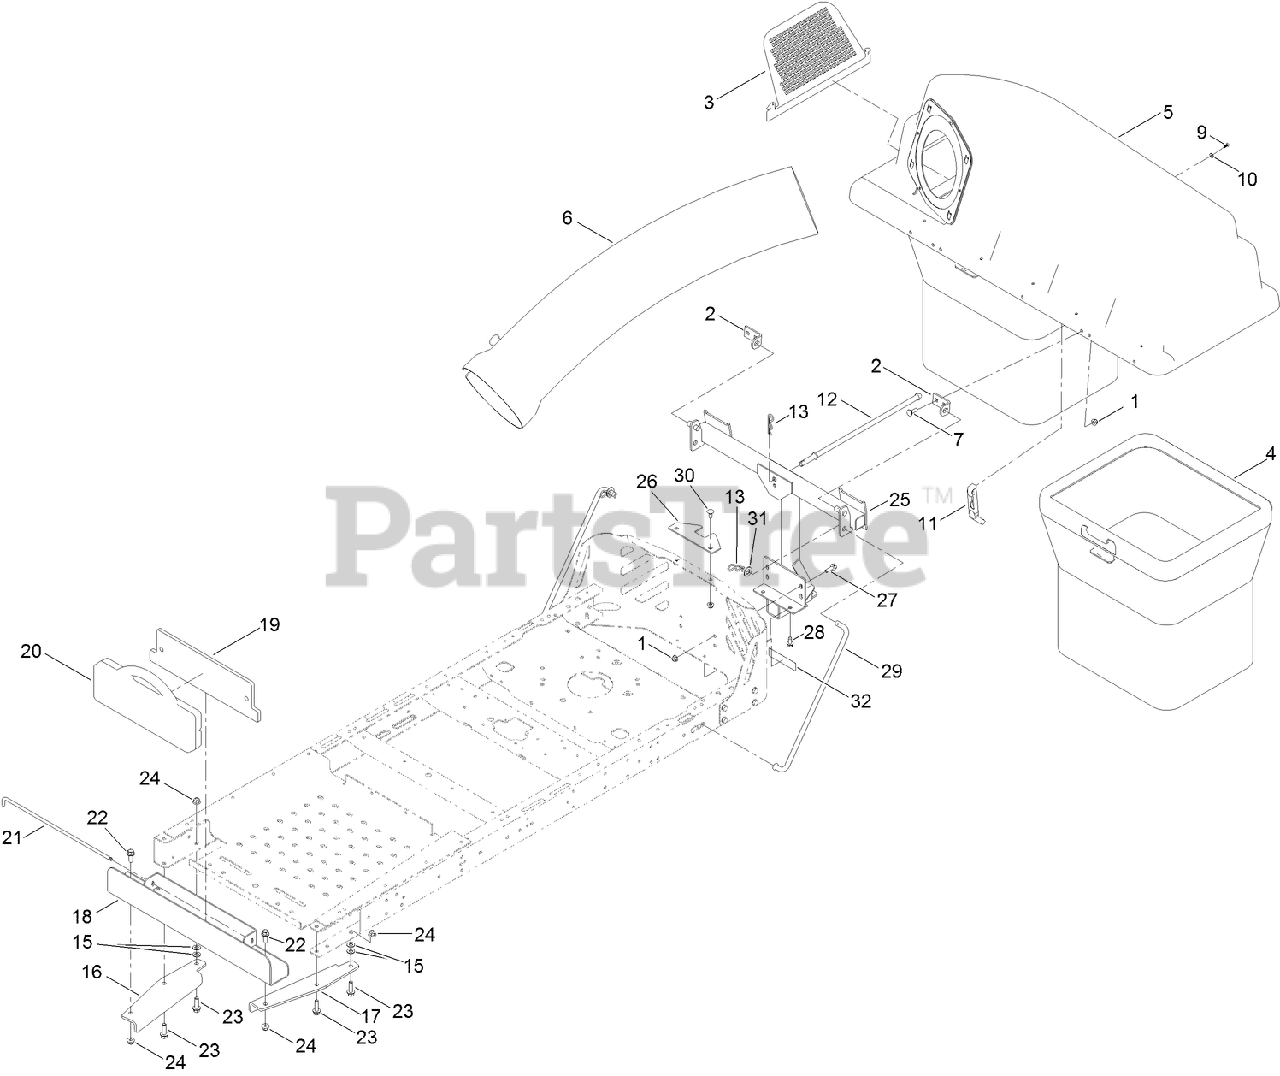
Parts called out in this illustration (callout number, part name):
1	NUT-HF, NI
2	BRACKET-PIVOT, HOPPER
3	SCREEN-BAGGER
4	BAG ASM
5	BAGGER TOP ASM
6	TUBE-BAGGER
7	BOLT-CARR
9	SCREW-PLASTIC, PTH
10	WASHER-FLAT
11	LATCH-RUBBER
12	ROD-HOOD, DOWN (HOLD)
13	PIN-HAIR
15	WASHER-FLAT
16	BRACKET-BAGGER WEIGHT, RH
17	BRACKET-BAGGER WEIGHT, LH
18	CHANNEL-WEIGHT, BAGGER
20	WEIGHT-35 POUND
21	PIN-WEIGHT
22	SCREW-HHF
23	SCREW-HHF
24	NUT-HF, NI
25	PIVOT FRAME ASM
26	BRACKET-STABILIZER
27	SCREW-HHF
28	SCREW-HWHTF
29	ROD-SUPPORT
30	BOLT-CARR
31	WASHER-FLAT
